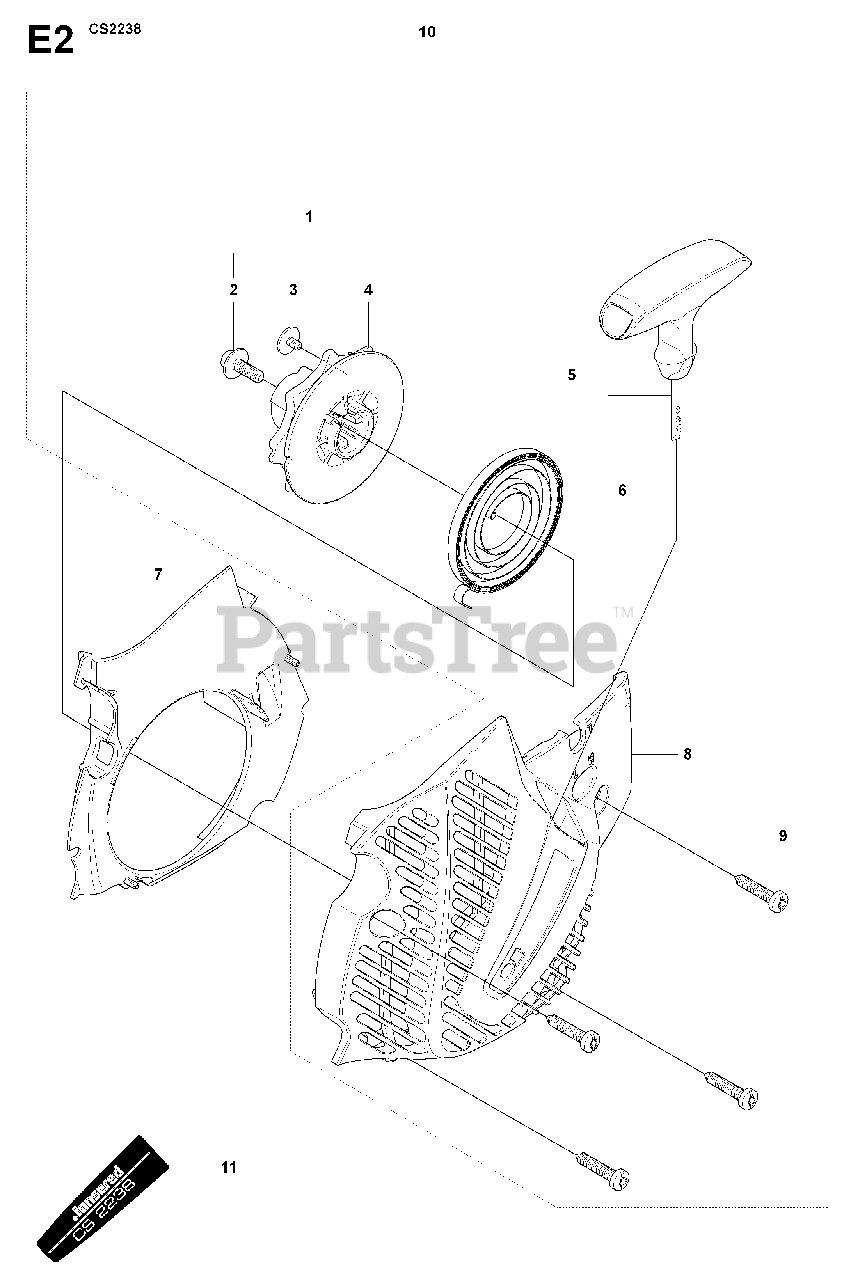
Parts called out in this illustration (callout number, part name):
1	KIT, STD STARTER
4	STARTER PULLEY
6	SPRING STARTER
9	SCREW M5.38-14X22.225MM
